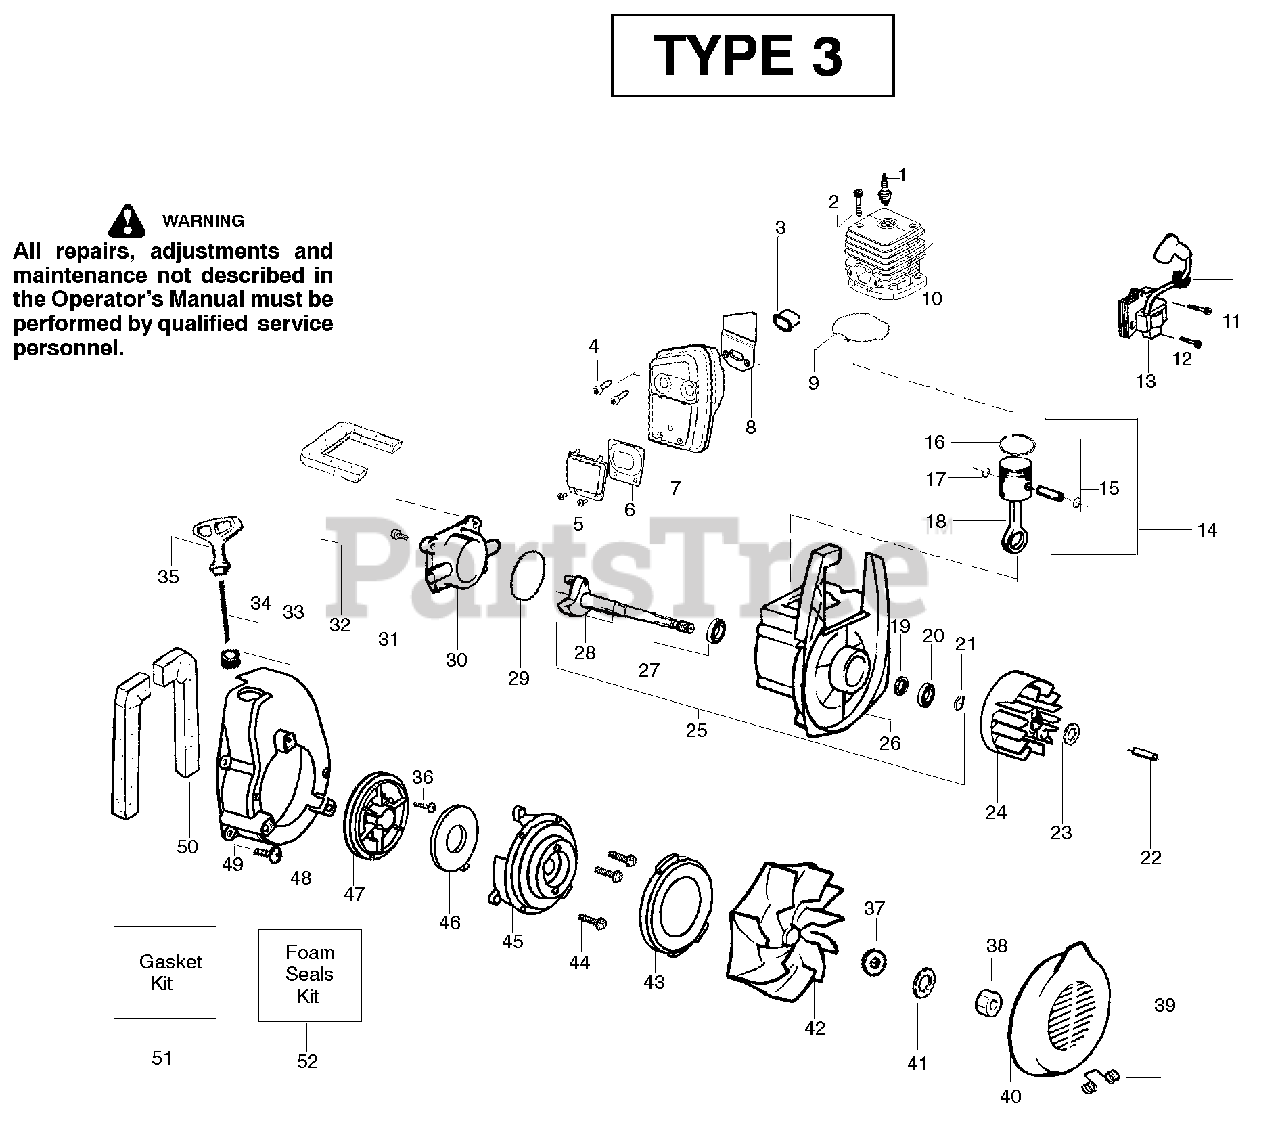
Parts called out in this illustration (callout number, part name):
1	Spark Plug (RCJ-6Y)
3	Insulator-Heat
4	Screw-Muffler-Internal
6	Kit-Spark Screen
7	Kit-Muffler
8	Gasket-Baffle (kit)
9	Gasket-Cylinder (kit)
10	Kit-Cylinder
11	Grommet-Ign. Module
12	Screw-Ignition Module
13	Ignition Module
14	Kit-Piston/Rod
15	Kit-Piston
16	Piston Ring
17	Retainer-Piston Pin
18	Assy-Connecting Rod
19	Seal-Crankcase
20	Bearing-Outer
21	Retainer Ring-C'chaft
22	Spacer-Flywheel
24	Assy-Flywheel
25	Assy-Crankcase/Crank shaft
26	Assy-Crankcase
27	Bearing-Inner
28	Assy-Crankshaft
29	O-ring-C/case (kit)
30	Cover-Crankcase
31	Screw
32	Foam-219mm (kit)
33	Eyelet-Flange
34	Kit-Rope
35	Handle-Starter
36	Screw-Rope
37	Washer-Belleville
39	Spring-Return Cover
40	Inlet Door
42	Kit-Impeller Assy.
43	Seal-Ring
45	Housing-Pulley
46	Spring-Starter
47	Kit-Starter Pulley
48	Fan Housing
49	Screw
50	Foam-182mm (kit)
51	Kit-Gasket
52	Kit-Foam Seals
